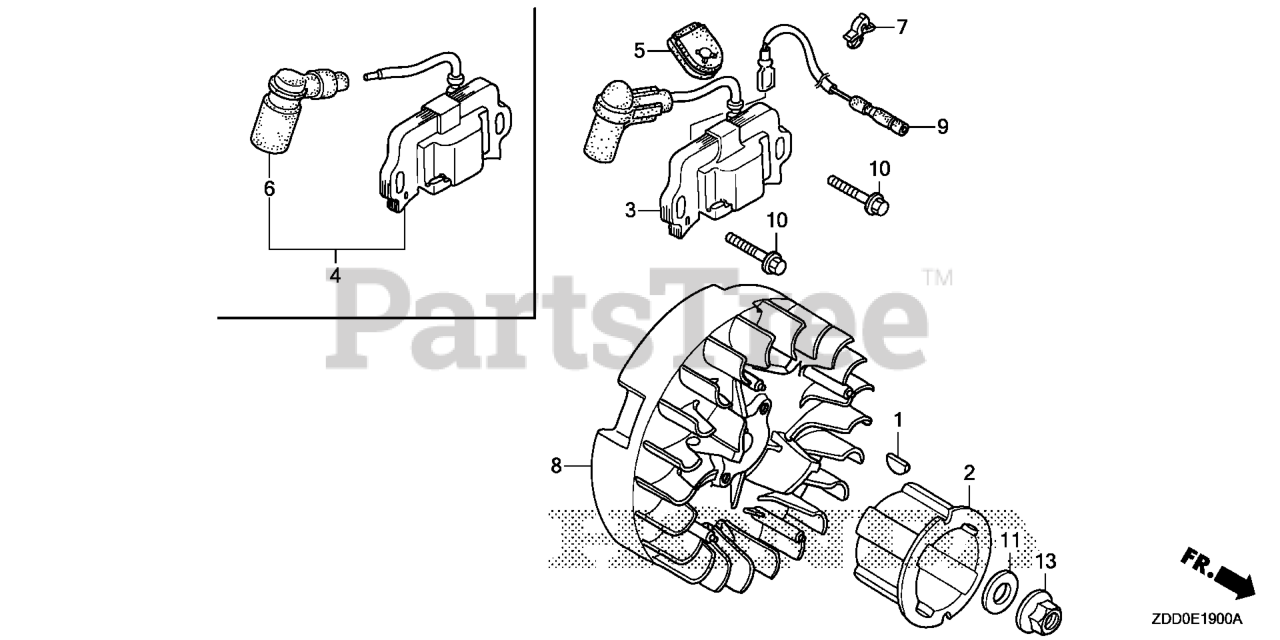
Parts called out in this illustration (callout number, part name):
1	KEY, SPECIAL
2	PULLEY, STARTER
4	COIL ASSY., IGNITION
5	GROMMET, WIRE
6	TERMINAL ASSY., IGNITION
10	BOLT, FLANGE (6X20) (CT200)
13	NUT, FLANGE (12MM)
